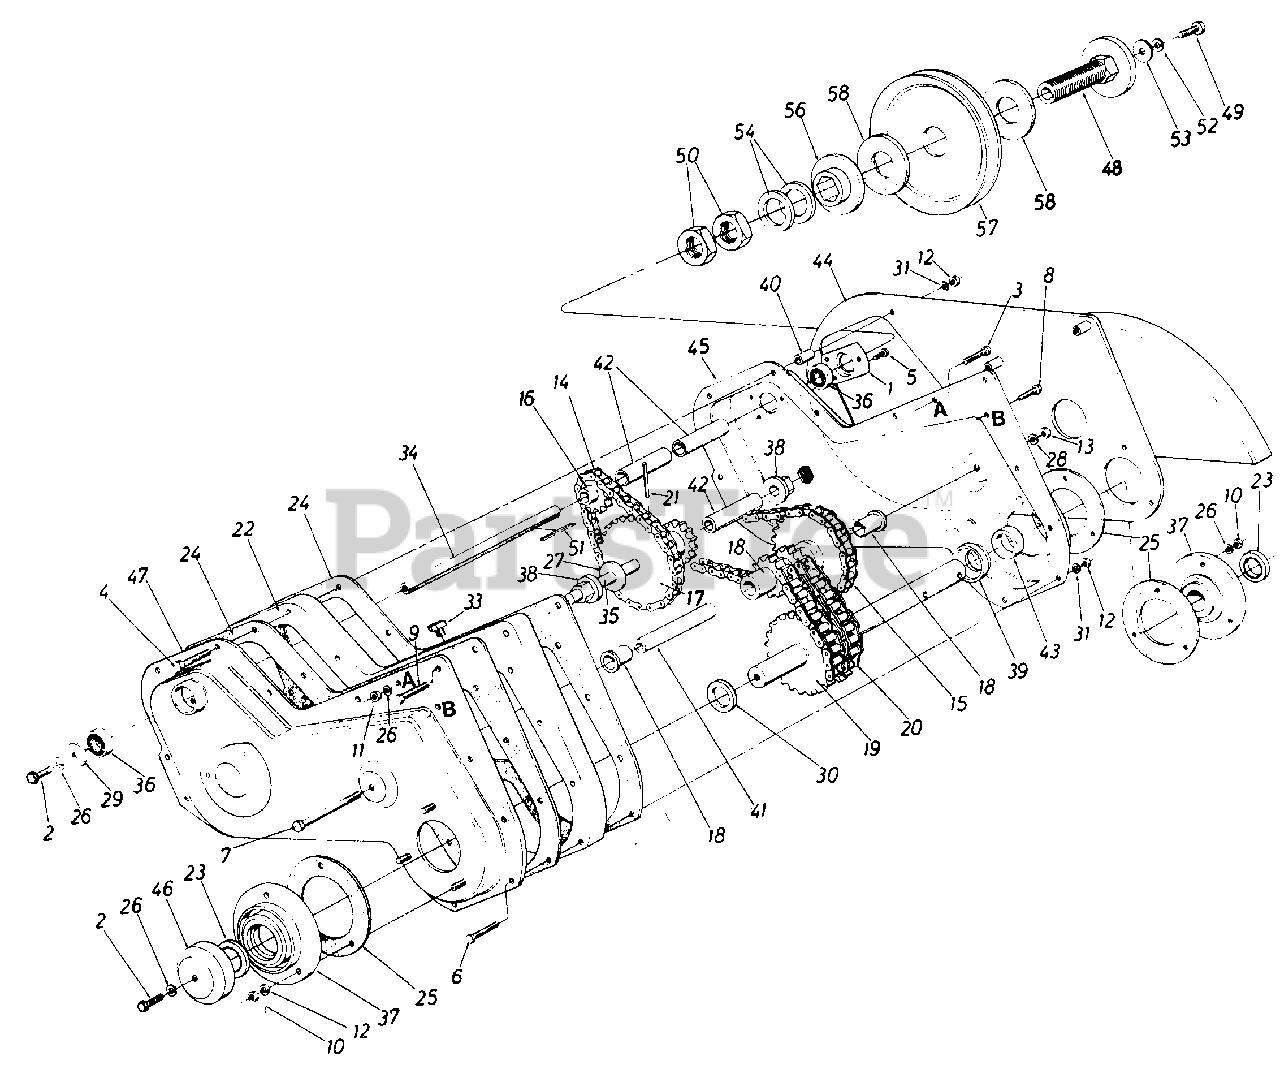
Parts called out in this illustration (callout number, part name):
1	Bearing Housing 1-3/8" Dia.
2	Hex Bolt 5/16-18 x .88" Lg. Spec.
3	Hex Bolt 5/16-18 x 1.50" L-g.*
4	Hex Bolt 1/4 20 x 2.75" Lg.*
5	Hex Wash. S-Tap. Scr. 1/4-20 x .50" Lg.
6	Hex Bolt 1/4-20 x 1.50" Lg.*
7	Hex Bolt 3/8-16 x 4.5" Ly.
8	Hex Wash. Hd. Bolt 1/4-20 x 1.5" Lg.
9	Hex Wash. TT-Tap Scr. 5/16 18x 1.75" Lg.
10	Hex Cent. L. Nut 5/16-18 Thd.
11	Hex Nut 5/16-18 Thd.*
12	Hex Nut 1/4 20Thd.*
13	Hex Nut 3/8-16 Thd*
14	#41 Chain 1/2" Pitch x 34 Links- Endless
15	#42 Chain 1/2" Pitch x 48 Links- Endless
16	Sprocket 10Tooth.500" Pitch
17	10 & 28 Teeth Sprocket Ass'y.
18	8-2 . 28 Sprocket Sleeve Ass'y.
19	18-2 Sprocket Shaft Ass'y.
20	#50-2 Chain 5/8" Pitch x 28 Links- Endless
21	Spring Pin Spir. 1/4" Dia. x 1.50" Lg.
22	SpacerBlock-TillerHousing
23	Oil Seal Double Lip 1-1/4" Dia.
24	Gasket for Tiller Housing
25	Gasket for Brg.Housing
26	L.Wash. 5/16" I.D.*
27	Fl.Wash. .640" I.D. x 1.24" O.D.
28	L.Wash. 3/8" I.D. Heavy Duty
29	Fl.Wash. .344" I.D. x .1.125"
30	Special Washer
31	L.Wash. 1/4" I.D.*
33	Vent Plug
34	Jack Shaft .525" I.D. x 7.78" Lg.
35	Sprocket Shaft .63" Dia. x 5.0" Lg.
36	Ball Brg. .62" I.D. x 1.38" O.D.
37	Bearing Housing- 1-1/4"
38	Hex Flange Brg.
39	Spacer 1.25" I.D. x 2.0" 0 D.
40	Spacer .28" I.D. x .62" O.D. x .90" Lg.
41	Spacer .38" I.D. x .62'l O.D. x 3.44" Lg.
42	Spacer .62" I.D. x .88" O.D. x 1.56" Lg.
43	Spacer 1.25" I.D. x 1.62" O.D. x .50" Lg.
46	Dust Cap .320" Dia. Hole
49	Hex Bolt 5/16-18 x 1.25" Lg.(Grade 5)
50	Hex Jam Nut 1.0-14 x 28 Thd.
51	Sq. Key 3/16 x 1.50" Lg.
52	L.-Wash. 5/16" I.D.*
53	Fl.Wash. .344" I.D. x 1.125" O.D.
54	Spring Bell Wash. 1.0" I.D. x 2.0" O.D.
56	Floating Disc 3-1/4" O.D. x 1.0" I.D.
57	5/8 V-Pulley 1.50" I.D. x 6.50"
58	Friction Pad 3-1/4" O.D. x 1-3/8 " I . D .
